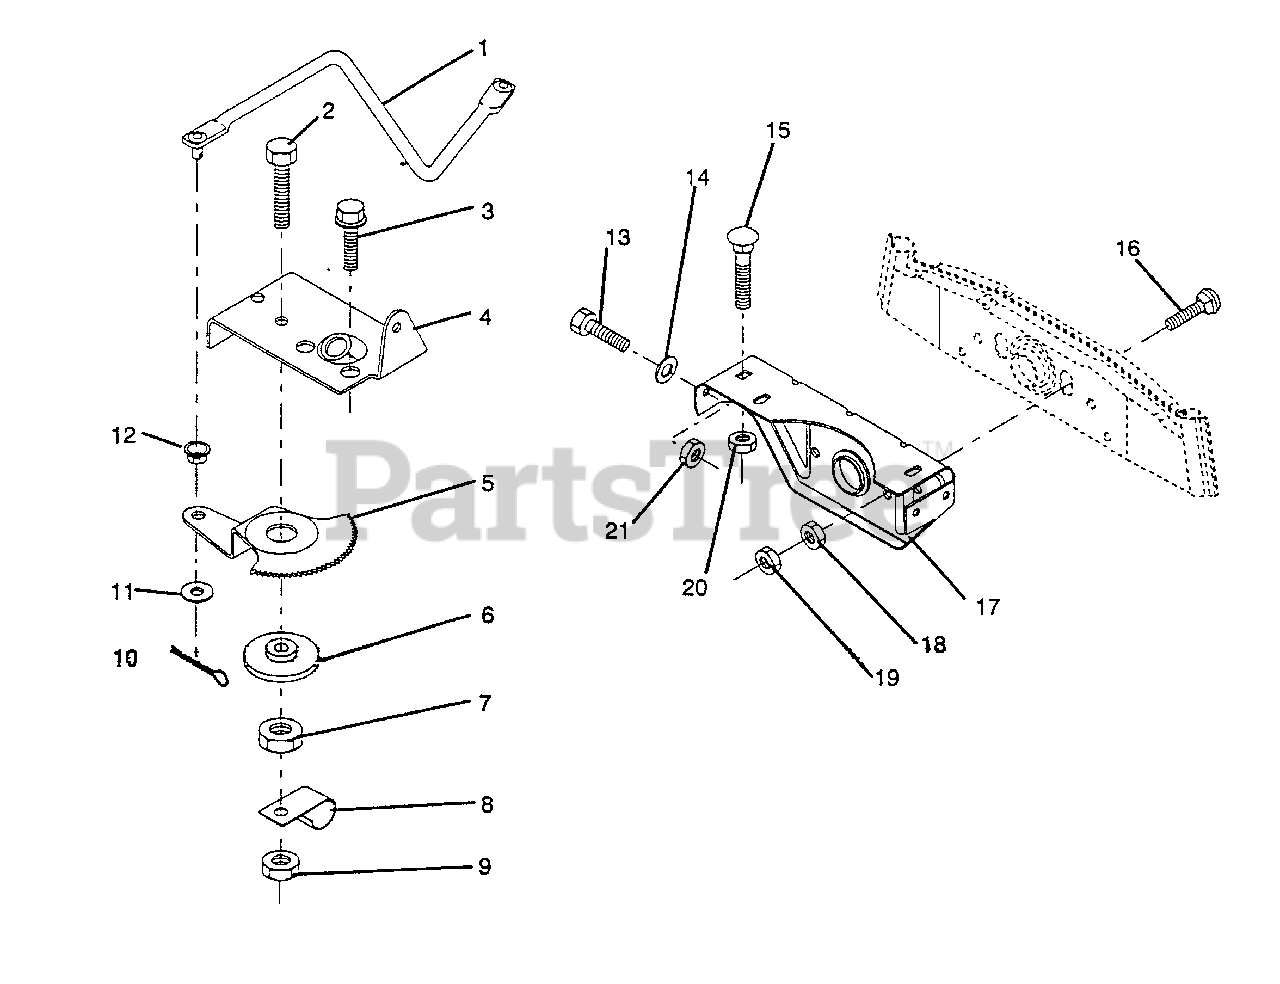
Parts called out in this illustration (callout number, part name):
1	Link, Drag
2	1-3/4 Bolt, Fin. Hex 1/2-13
3	Screw Hex Thrdrol 5/16-18 x 1/2
4	Plate,Steering Support
5	Gear, Sector
7	Nut, Heavy Hex Top Lock 1/2-13 UNC
8	Clip, Insulated
9	Nut, Crownlock 3/8-16
10	Pin, Cotter 1/8 x 3/4
11	Washer, 13/32 x 13/16 x 16 Ga.
13	Bolt, Hex Hd. 5/16-18 UNC x 3/4
14	Washer 11/32 x 7/8 x 16 Ga.
15	Bolt, Carriage 3/8-16 UNC x 3/4
16	Bolt, Carriage
17	Support, Front Axle
18	Nut, Fin. Hex 3/8-16 UNC
19	Nut, Centerlock 3/8-16 UNC
20	Nut, Crownlock 3/8-16 UNC
21	Nut, Crownlock 5/16-18
